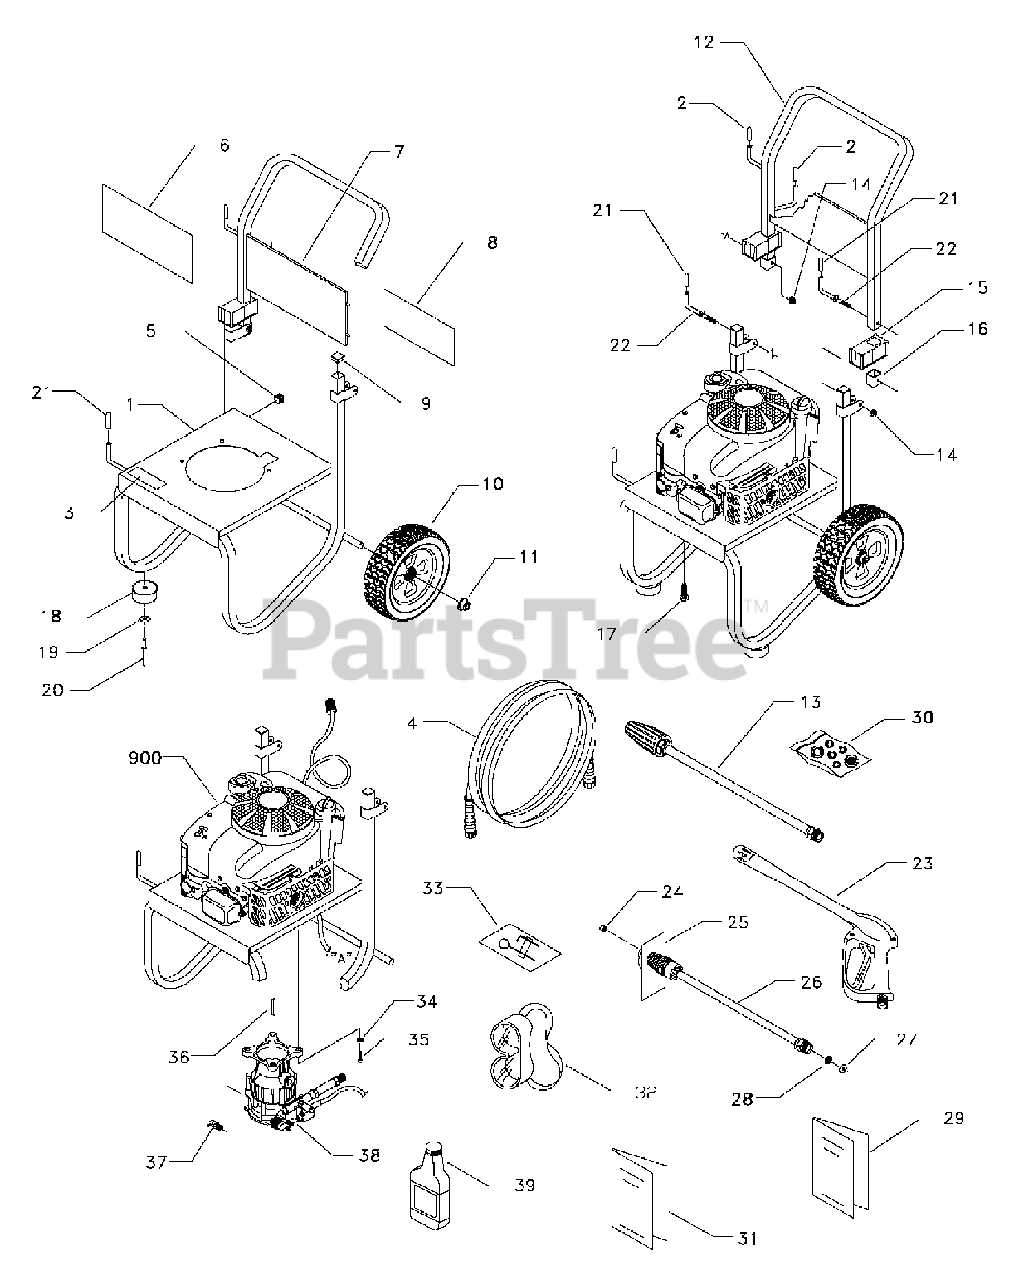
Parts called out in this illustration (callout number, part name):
1	BASE, Snapper Red
2	CAP, Vinyl Black
3	DECAL, Cool Down
4	HOSE, 1/4" X 25'
5	GROMMET, Chemical Hose
6	DECAL, Logo 2400 PSI
7	BILLBOARD, Plastic
8	DECAL, Instructions
9	PLUG, Plastic
10	WHEEL, Plastic, 3" X 10"
11	PUSHNUT, 1/2"
12	HANDLE, Snapper Red
13	WAND, Turbo
14	LOCKNUT, 1/4"-20, Flange
15	HINGE, Cover
16	CAP, Tube End
17	TAPTITE, 3/8" - 16 x 1-1/4"
18	MOUNT, Rubber Foot
19	WASHER, Fender
21	CAP, Vinyl, Black
22	HOOK, Chemical Bottle
23	GUN, High Pressure
24	NOZZLE, 1.10 White Rplcemt
25	HANG TAG, Nozzle
26	WAND, Adjustable Nozzle
27	O-RING, Hi-Pressure
28	SCREEN, Gun Inlet
29	MANUAL, Owners
30	KIT, O-Ring Maintenance
31	MANUAL, B & S Engine
32	GLASSES, Safety
33	KIT, Nozzle Cleaning
34	LOCK WASHER, M8 Ribbed
35	SOCKET HEAD CAP SCREW, 5/16" - 24 x 1"
36	KEY, 3/16" square x 1.50"
37	VALVE, Thermal Relief
38	PUMP, Assembly (see pages 18-19)
39	OIL, 20oz.
0560	PLUG
900	ENGINE, NSP
